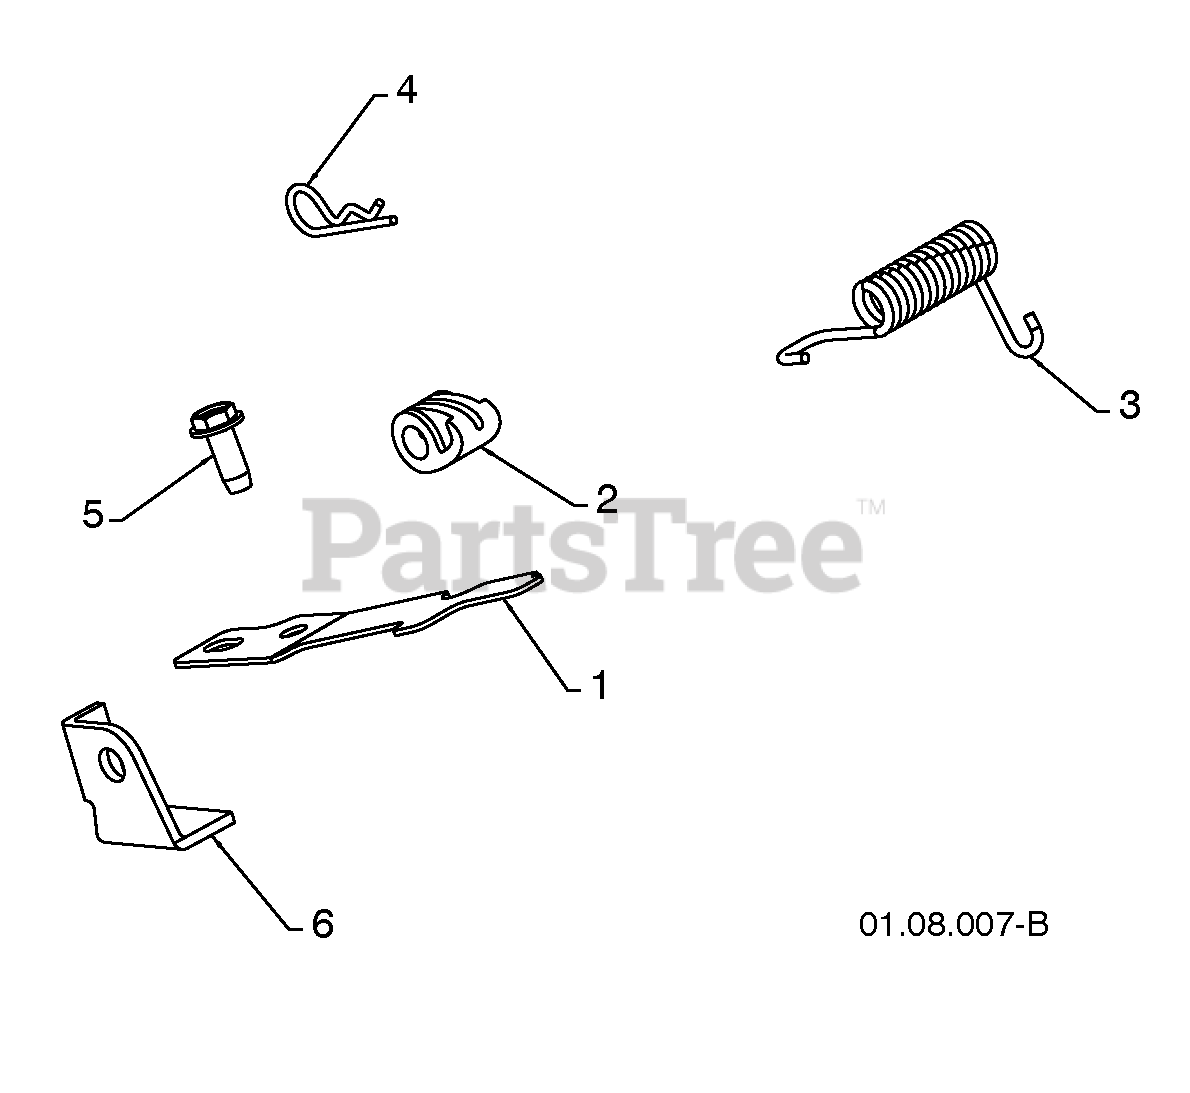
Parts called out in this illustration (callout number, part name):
1	INTERLOCK SPRING
2	INTERLOCK CAM
3	TORSION SPRING
4	RETAINER
5	SCREW 1/4-20 X .625
6	INTERLOCK STOP
